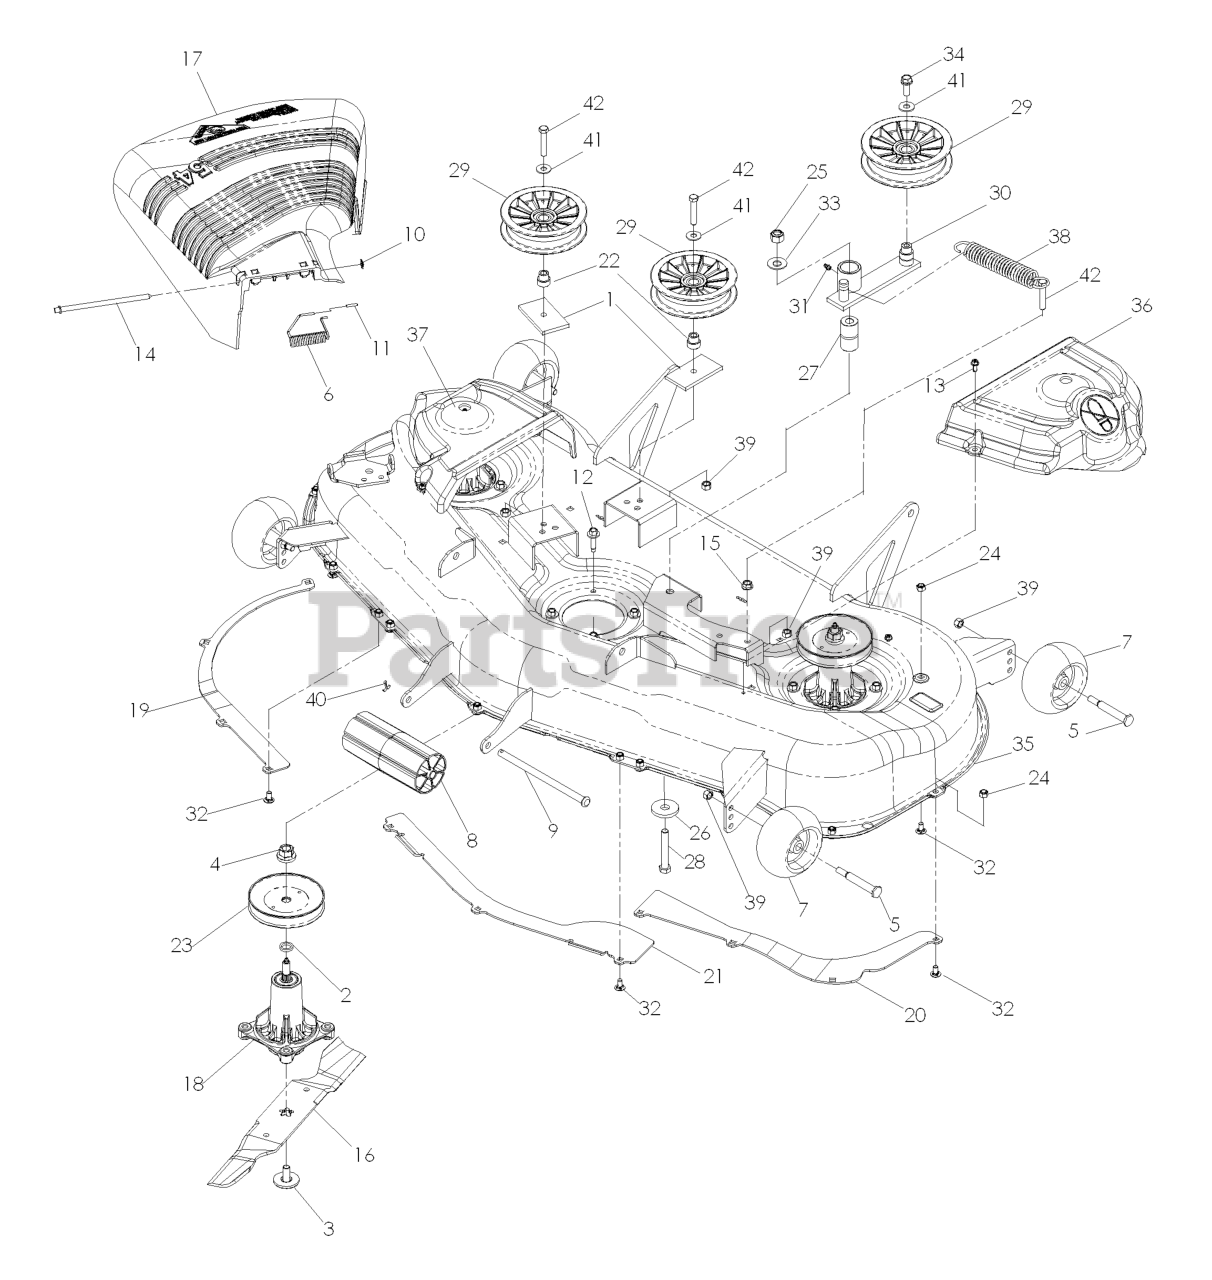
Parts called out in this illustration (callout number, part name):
1	SUPPORT PLATE
2	WASHER-SPACER
3	BOLT 7/16 ASM BLADE
4	LOCKNUT - 9/16
5	BOLT, SHOULDER
6	TORSION SPRING
7	WHEEL GAGE DONUT
8	NOSE ROLLER 48"
9	NOSE ROLLER ROD
10	PUSH NUT
11	CAP-SLEEVE
12	WASHER HEAD SCREW
13	SCREW- 1/4-20 X 5/8
14	ROD.HINGE
15	NUT 3/8C WHIZ
16	BLADE STANDARD 54
17	DEFLECTOR, 54"
18	MANDREL GREASABLE
19	BAFFLE, RIGHT 54"
20	BAFFLE LEFT 54
21	BAFFLE, CENTER, 54"
22	IDLER BUSHING
23	PULLEY
24	NUT 5/16 NYLOC
25	NUT 1/2-13 HEX NYLOC ZD
26	WASHER, SUPPORT
27	PIVOT BUSHING
28	HCS 1/2C X 3 1/4
29	PULLEY - IDLER, NYLON
31	ZERK
32	CARRIAGE BOLT 5/16C X 5/8"
33	WASHER 1/2 FLAT
34	4CS 3/8C X 1 SERRATED HEAD
35	DECK W/DECALS 54" HUS ORANGE
36	BELT SHIELD, LT
37	BELT SHIELD, RT
39	NUT 3/8-16 NYLOC
40	RP_COTTER PIN 1/8 X 3/4
41	WASHER 3/8 FLAT
42	HCS 3/8C X 2
